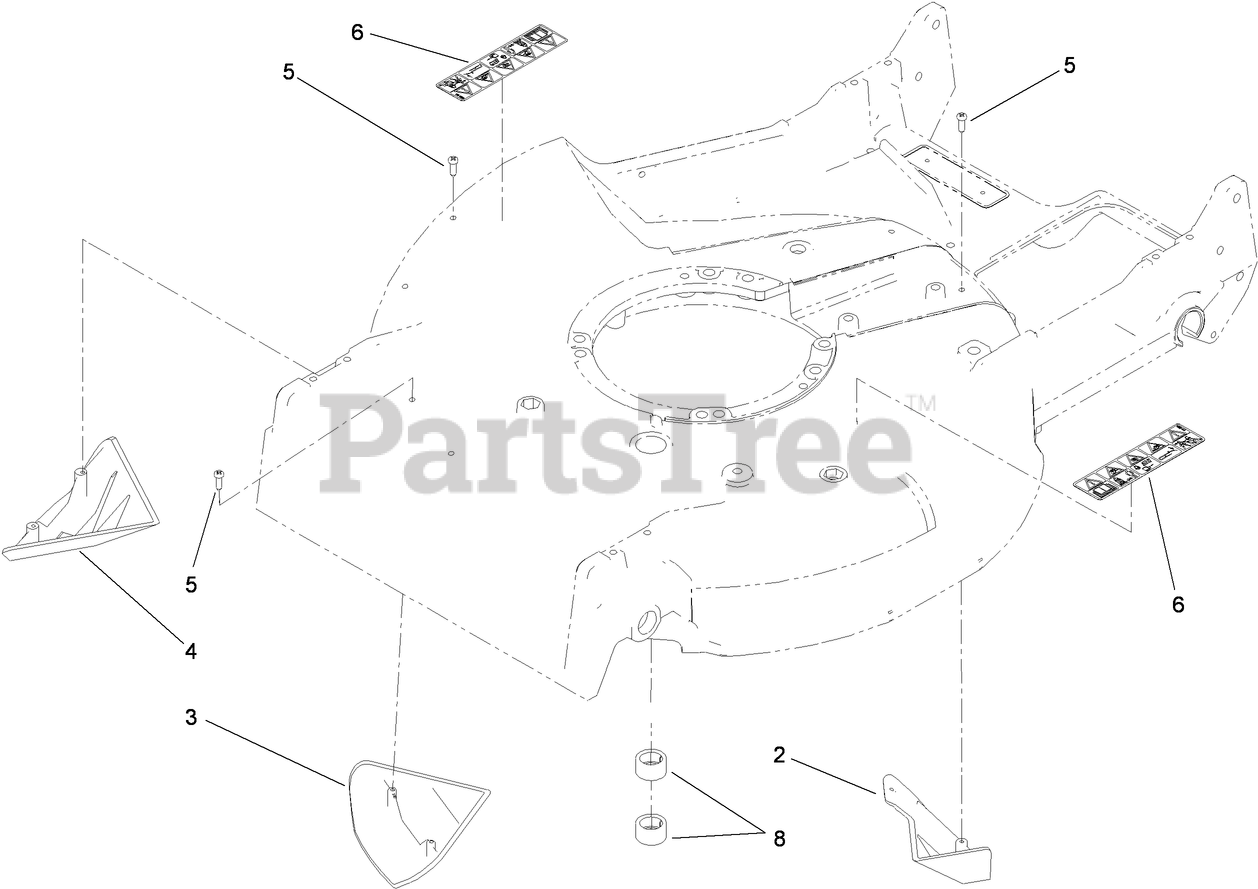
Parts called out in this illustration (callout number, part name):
2	KICKER-REAR
3	KICKER-FRONT
4	KICKER-RH
5	SCREW-PPH
6	DECAL-DANGER
8	BEARING
